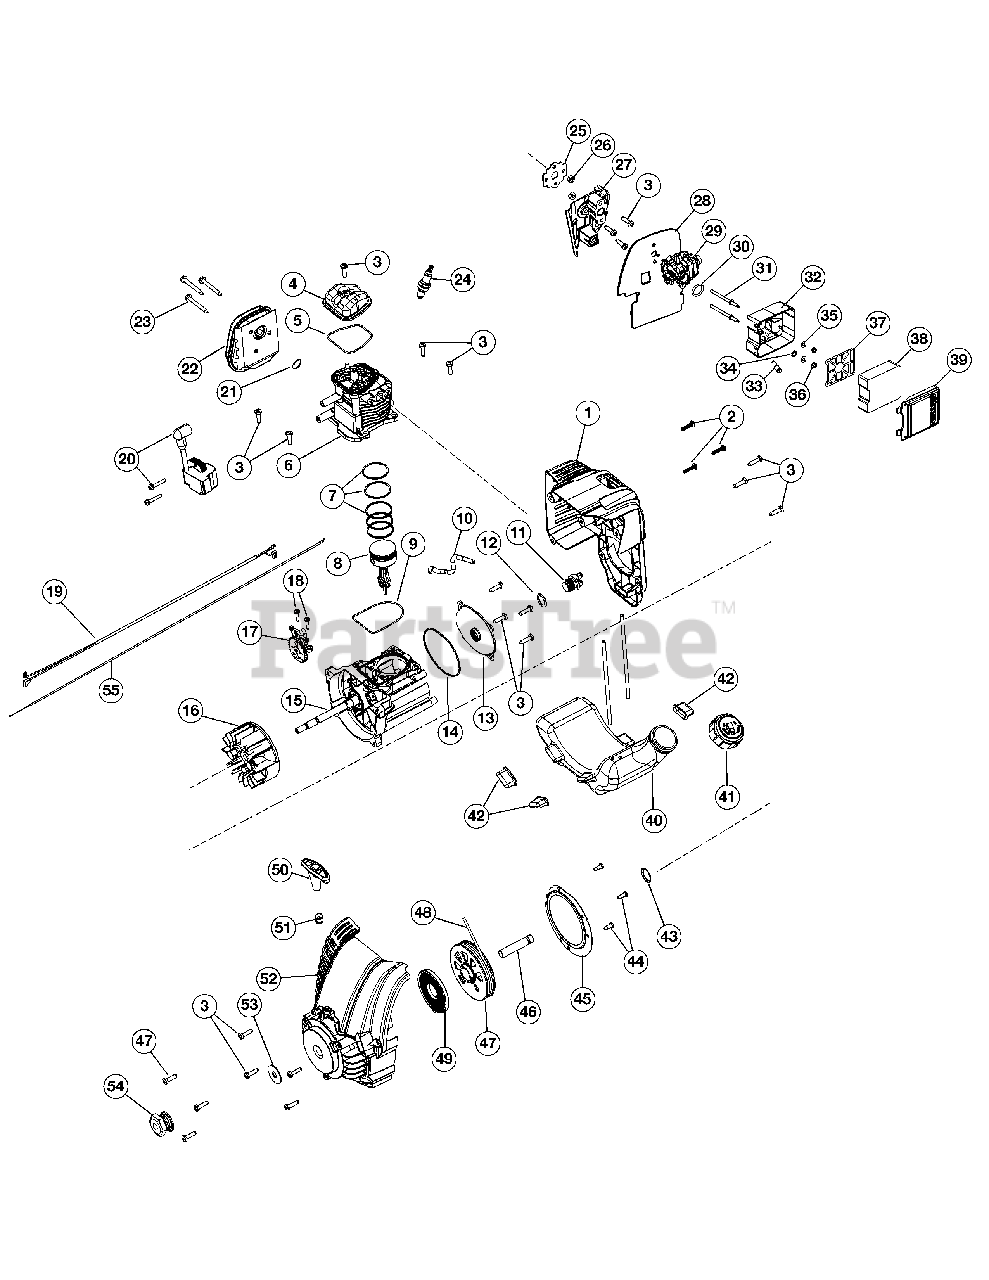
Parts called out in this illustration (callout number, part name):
1	Engine Cover Assembly (includes 2 & 3)
2	Cover Screw
3	Screw
4	Rocker Cover
5	Rocker Cover O-Ring
6	Cylinder Assembly (includes 3, 5 & 9)
7	Piston Ring Assembly
8	Piston Assembly (includes 7)
9	Cylinder O-Ring
10	Breather Hose
11	Oil Plug (includes 12)
12	Oil Plug O-Ring
13	Crankcase Cover
14	Crankcase Cover O-ring
15	Crankcase Assembly (includes 9, 10, 14 & 16)
16	Flywheel Assembly
17	Cam Bracket Assembly (includes 18)
18	Cam Bracket Screw
19	Lead Wires
20	Module Assembly
21	Muffler Gasket
22	Muffler Assembly (includes 21 & 23)
23	Muffler Screw
24	Spark Plug
25	Insulator Gasket
26	Nut
27	Insulator (includes 28)
28	Carburetor Gasket
29	Carburetor w/Primer
31	Air Filter Mounting Screw
32	Air Cleaner Cover Assembly (includes 33, 34 & 37-39)
33	Breather Tube
34	Grommet Washer
36	Nut
37	Air Filter Plate
38	Air Filter
39	Air Filter Cover
40	Fuel Tank Assembly w/Fuel Lines (includes 41)
42	Fuel Tank Pads
43	Push Nut
44	Pressure Plate Screw
45	Pressure Plate (includes 44)
46	Spacer
47	Starter Assembly (includes 48)
49	Recoil Spring
50	Handle
52	Starter Housing Assembly (includes 3 & 43-51)
53	Washer
54	Drive Shaft Pulley
55	Throttle Cable
